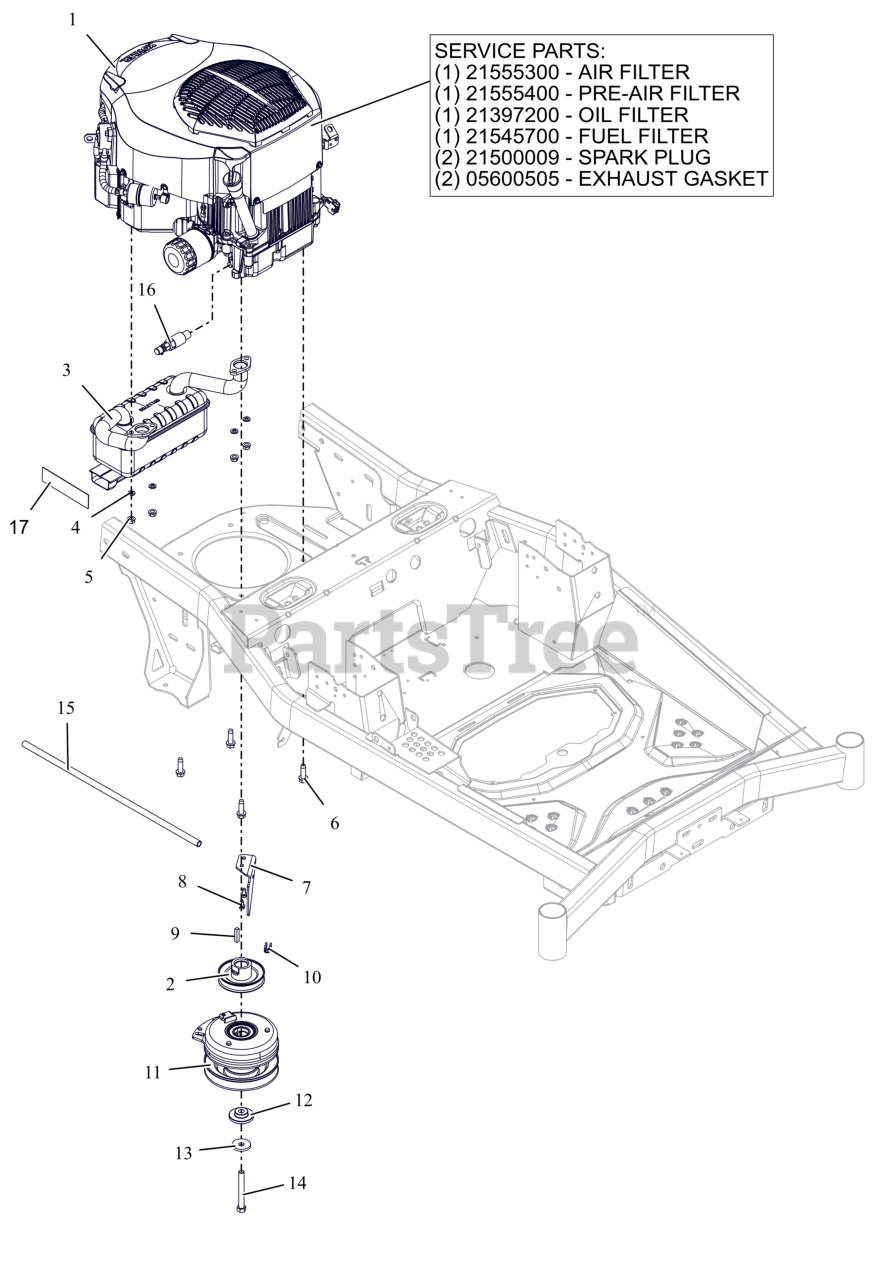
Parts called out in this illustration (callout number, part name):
1	ENGINE, KOHLER - KT740
1	AIR FILTER, KOHLER
1	PRE CLEANER, KOHLER
1	FILTER, OIL - KOH CV20
1	FILTER-FUEL KOHLER COURAGE PRO
1	PLUG, SPARK KOHLER
1	GASKET, MUFFLER KOHLER TWIN
2	WLDMT-PULLEY-4.831OD X1.003
3	MUFFLER, KOHLER
4	WSHR,LK-REG .312X.078 ZCC
5	NUT-LK-TOP-FLG .312-18 GF ZCC
6	SCR,TAP .375-16X1.25HWH TR ZCC
7	BRKT- CLUTCH STOP
8	SCR-TAP .25-20X.50 HWH ZCC
9	KEY-SQ .25 X 1.25 X .25 SAE
10	BSHG, CLUTCH
11	CLUTCH, WARNER-IXR-18211
12	BSHG-FLG .469X1.06X.574X2.0
13	WASHER, 7/16" SPRING DISK
14	BLT- HEX .44-20X3.50 G8 ZCC NT
15	HOSE- OIL DRAIN
16	DRAIN, OIL
17	TAPE, HEAT
